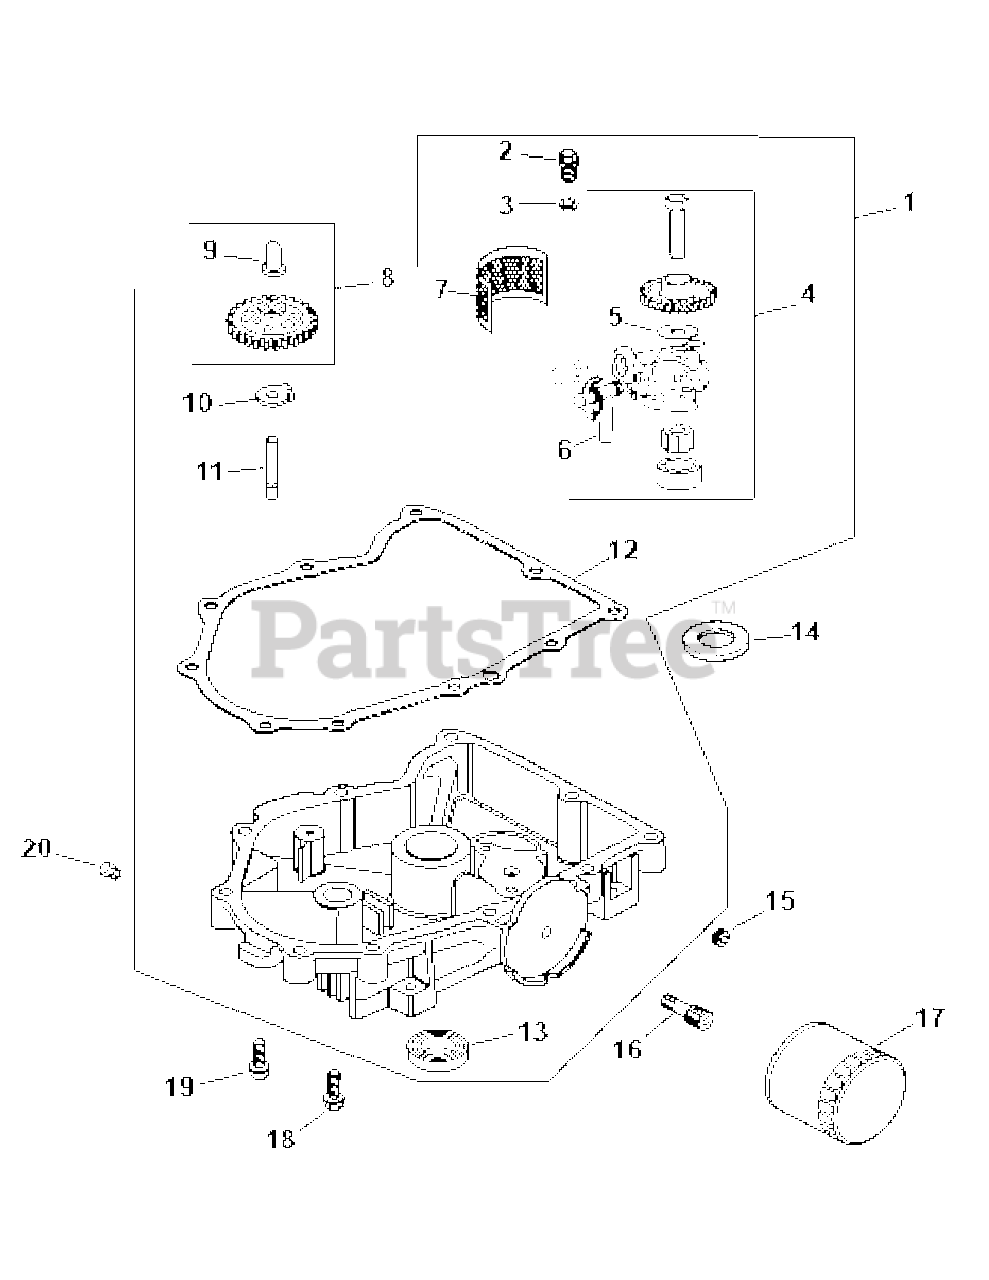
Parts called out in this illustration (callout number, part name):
1	Oil Pan w/Gasket Kit
2	Screw
4	Oil Pump Kit
6	Oil Pickup Tube
8	Governor Gear w/Pin Kit
11	Governor Gear Shaft
12	Oil Pan Gasket
13	Seal
16	Oil Filter Nipple
17	Oil Filter
18	Hex Flange Screw
19	Hex Flange Screw (M6 x 1.0 x 25)
